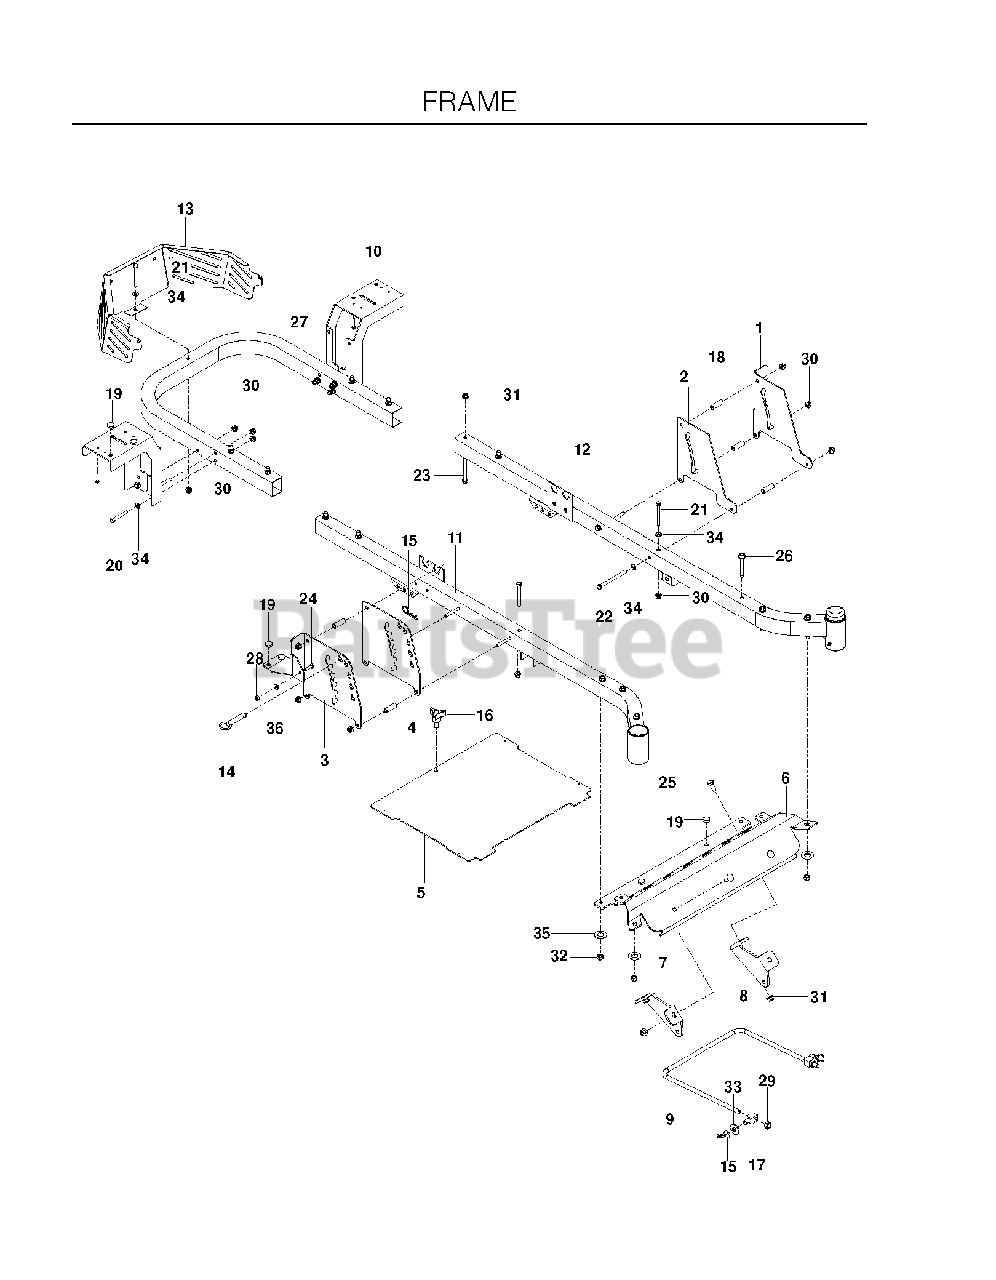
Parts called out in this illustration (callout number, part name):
1	PLATE, OUTER BRAKE, BLACK
2	PLATE, BRAKE LATCH, BLACK
4	PLATE, DECK HEIGHT, BLACK
5	PLATE, FOOT W/DECALS KZ
6	FOOT REST, MED BLUE
7	MOUNT, STRUT, RT, BLK
8	MOUNT, STRUT, LT, BLK
9	LINK, FRONT SUSP.
10	SUPPORT, FENDER, BLACK
11	FRAME, RT, BLUE
12	FRAME, LT, BLUE
13	GUARD, REAR, BLUE
14	HITCH PIN
15	HAIRPIN #4
16	KNOB W/STUD
18	SPACER, .334 ID X .5 OD X 1.5
19	GROMMET, BUMPER
20	CAPSCREW
21	HCS 5/16C X 2-3/4
22	HCS 5/16C X 4
23	HCS 3/8C X 3
24	HCS 1/4C X 1
25	RHSNB 3/8C X 1
26	ENGINE BOLT, SPECIAL
27	SCR #10-12X1-1/2HEX WASH HD ZD
28	NUT 1/4-20 NYLOC
29	7/16-14 HEX NUT W/NYLOC
30	5/16-18 NYLOC FLANGE NUT
31	NUT 3/8-16 HEX FLG NYLOC ZD
32	NUT HEX 3/8-16 NYLON, THIN
33	WASH USS FLAT 1/2
34	FLAT WASHER 5/16 SAE
35	WASHER 3/8 FLAT
36	WASHER 1/4 SAE
